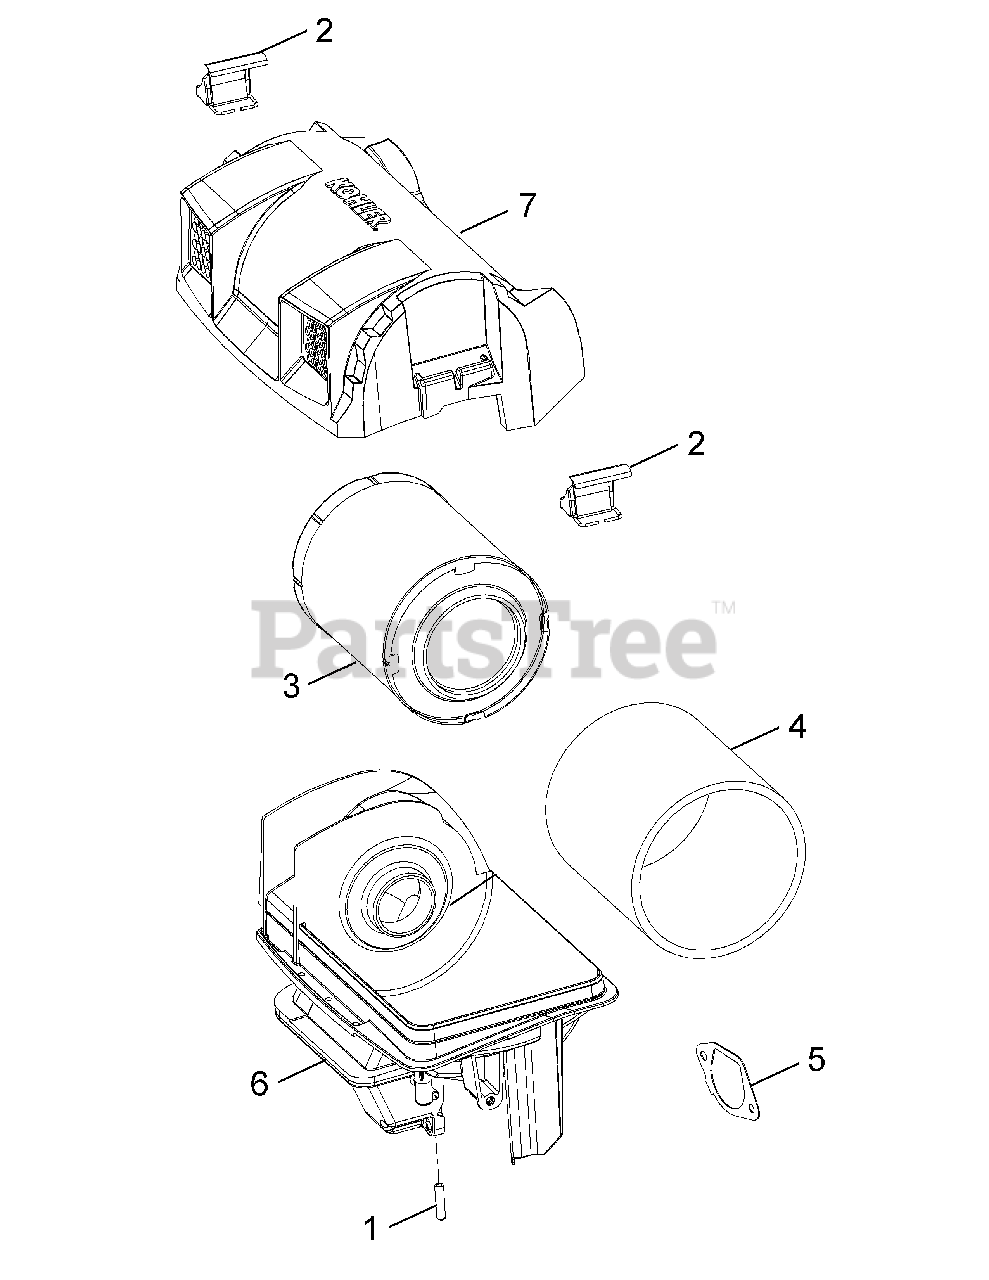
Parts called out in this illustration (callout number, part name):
2	Air Cleaner Cover Latch Assembly
3	Air Filter Element
4	Pre-Cleaner Element
5	Air Cleaner Base Gasket
6	Air Cleaner Base Assembly
7	Air Cleaner Cover
